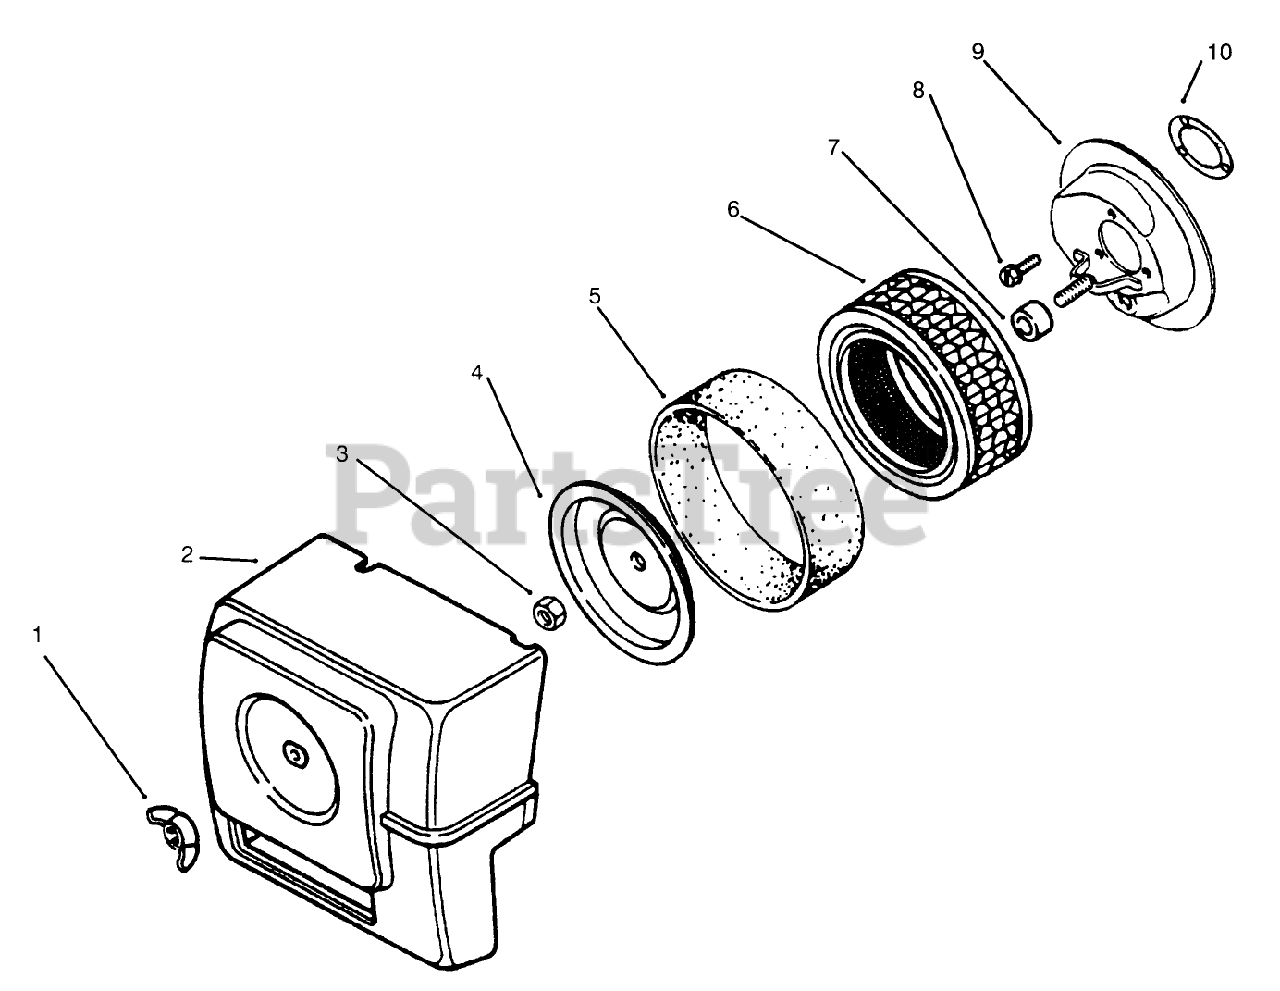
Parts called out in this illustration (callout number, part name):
1	Nut-Wing
2	Cover
3	Nut
4	Cover-Air Clean Element
5	Precleaner
6	Element
7	Seal
8	Screw
9	Base-Air Cleaner
10	Gasket
